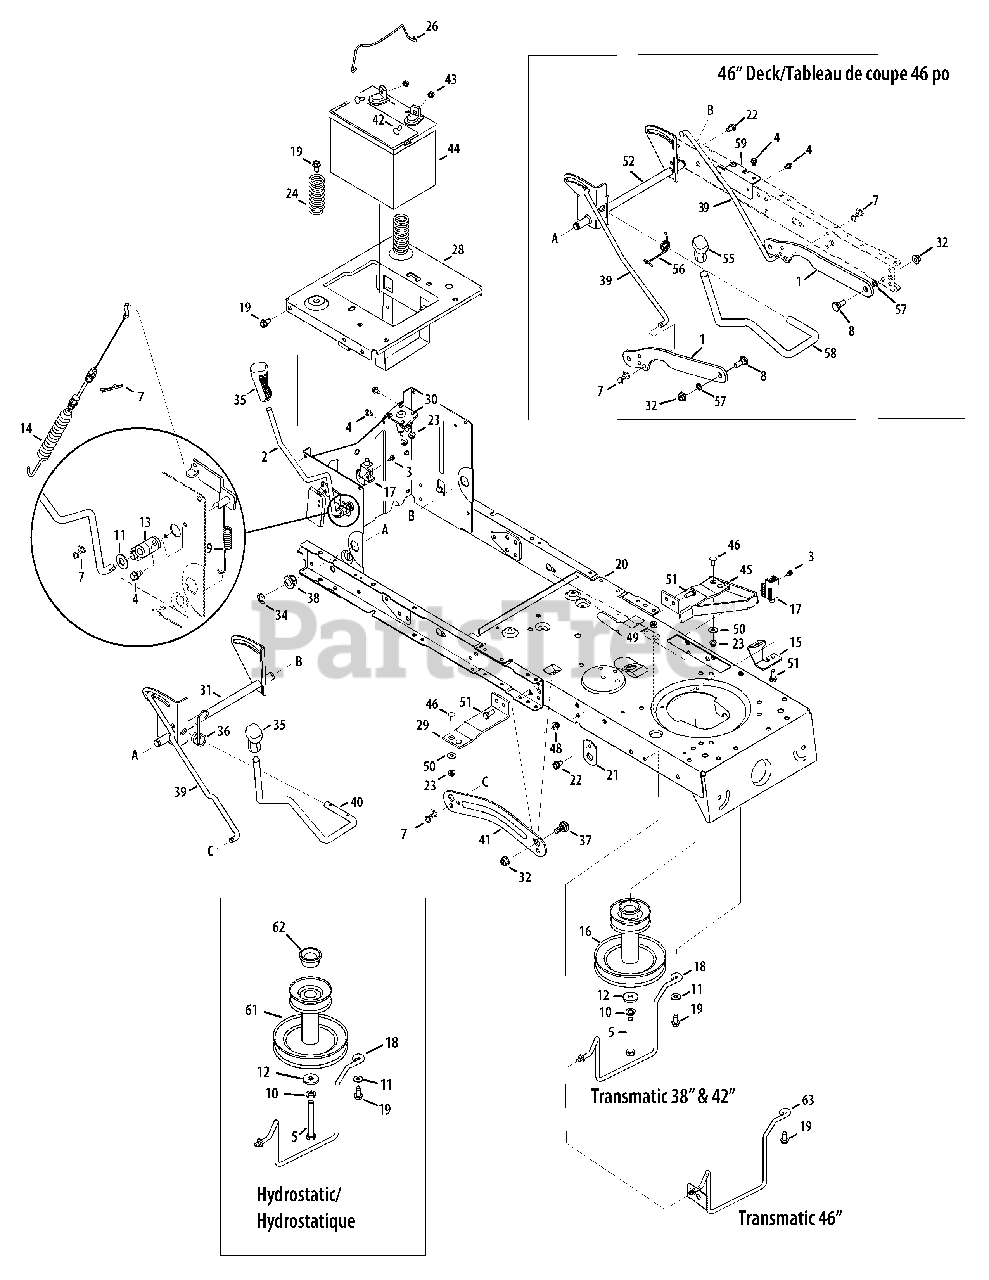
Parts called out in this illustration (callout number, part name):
3	Shoul der Screw #10-16 x .50" Lg.
4	Hex Wash S-Tapp Screw 1/4-20 x .50
5	Hex Hd. Cap Screw. 7/16-20 x 3.25 Gr. 5 (38/42")
7	Bow Tie Cot ter Pin
8	Shoulder Screw .5 x .270 : 3/8-16
9	Extension Spring
10	Lockwasher 7/16 ID
11	Flat Washer .385 ID x .87 OD x .06 (38" only)
12	Flat Washer .450 x 1.25 x .164
13	PTO Bea ing
14	Deck En gage ment Cable
15	Frame Support Bracket
16	Engine Pul ley 3.39 x 6.12 dia. (38/42")
17	Inte lock Switch
18	Belt Keeper Rod (38" Deck)
19	S-Tapp Screw 5/16-18 x .75
20	Frame
21	Pedal Support Bracket
22	Hex Wash HD TT Screw 5/16-18 x .625
23	Hex L-Flanged Nut 1/4-20 Gr. F, Ny lon
24	Compression Spring 1.28 x 3.125
26	Battery Hold Down Rod
28	Seat Frame Bracket
29	Running Board Bracket
30	Solenoid
32	Flange Lock-Nut 3/8-16 Gr. F, Ny lon
34	"E" Ring .625 Dia.
35	Handle Grip
36	Torsion Spring (38" & 42")
37	Shoulder Screw .625 x .175, 3/8-16
38	Hex Flange Bear ing .630 ID
39	Lift Rod
40	Deck Lift Handle(38"")
42	Hex Flg. Screw. 1/4-20 x .75 Gr. 5
43	Sems Hex Nut 1/4-20
44	Battery 245 CCA (Dry)
45	Support Bracket Ass'y
46	Carriage Bolt 1/4-20 x .62
48	Hex L-Flg Nut 5/16-18 Gr. F, Ny lon
49	Hex L-Nut 5/16-18
50	Flat Washer .28 x .74 x .063
51	Hex Screw 5/16-18 x .75
52	Lift Shaft (46" only)
56	Torsion Spring (46")
57	Flat Washer .395 x .62 x .063
58	Deck Lift Han dle (46")
59	Brace Bracket
61	Engine Pulley 3.39 x 6.12 dia. (38/42")
62	Spacer 1.0 x 1.4 x .825
63	Belt Keeper Rod (46" Deck)
